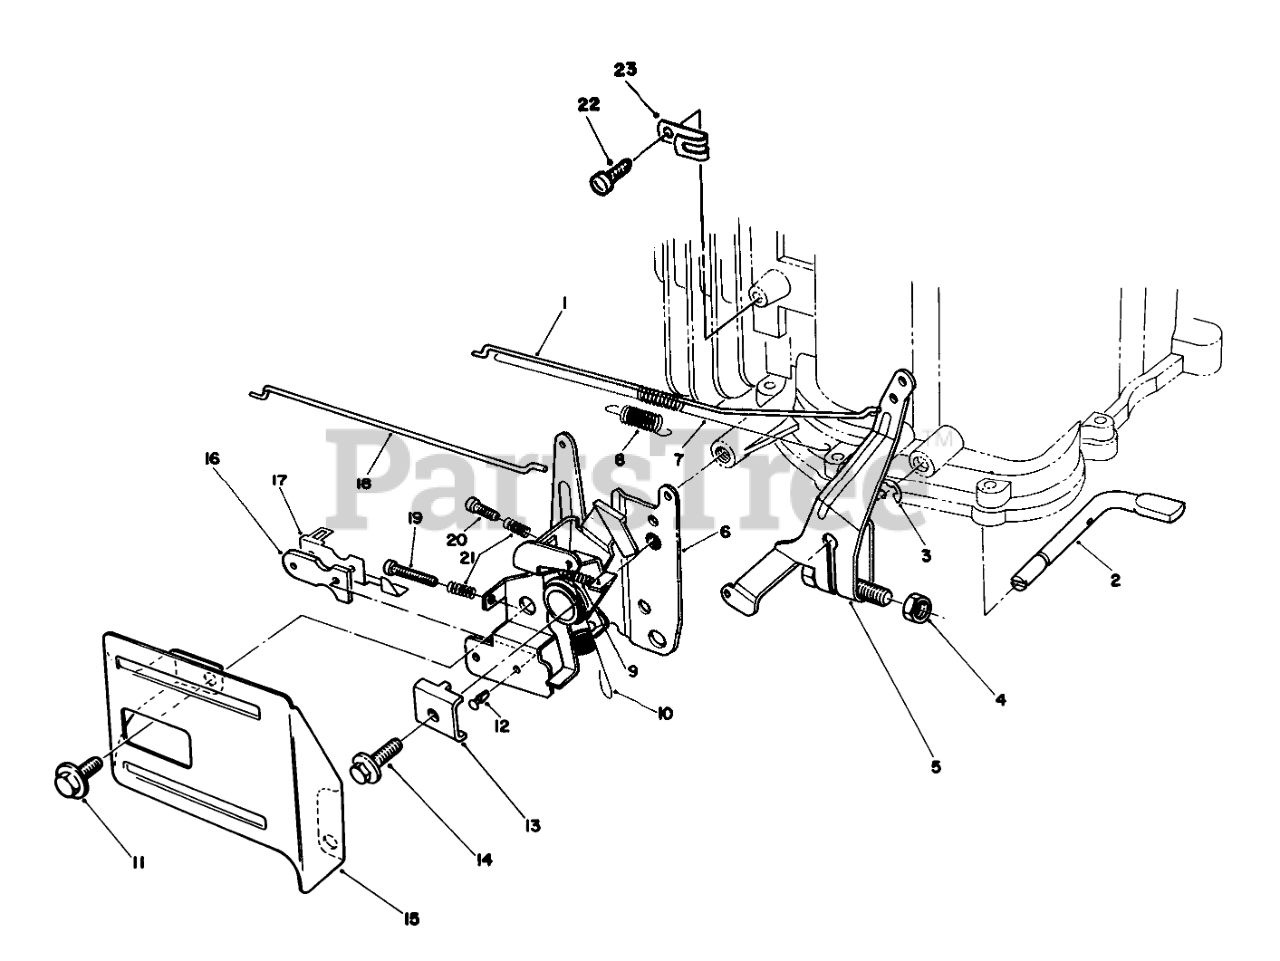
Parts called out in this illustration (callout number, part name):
1	Rod-Carburetor
2	SHAFT
3	E-RING
5	ARM ASM
6	THROTTLE
7	SPRING
8	SPRING
9	SPRING
10	SPRING
12	RIVET
13	CLAMP-CABLE
15	THROTTLE GUARD
16	INSULATOR-KILL SWITCH
17	TERMINAL-KILL SWITCH
18	Rod-Choke
19	SCREW
20	SCREW
21	SPRING
22	SCREW
23	Clamp
